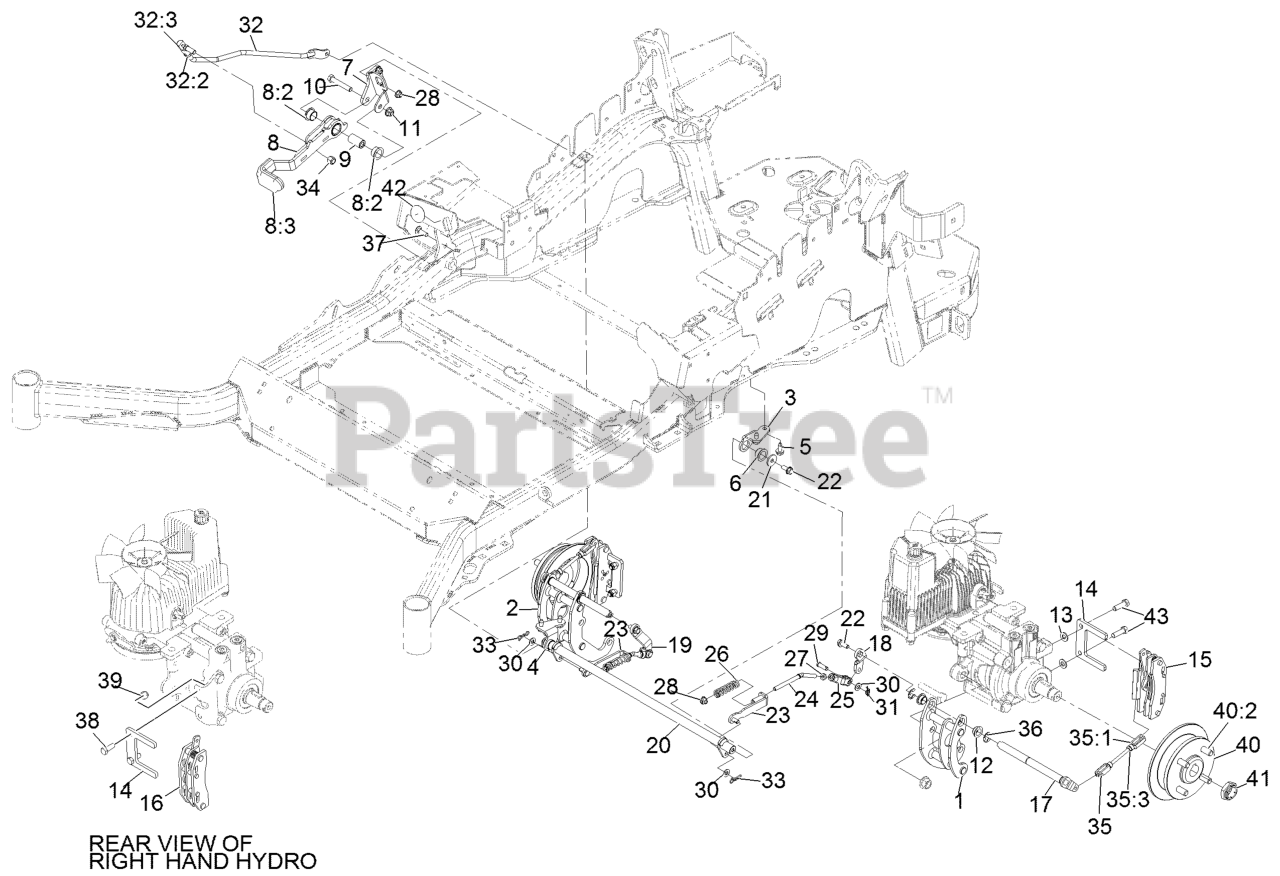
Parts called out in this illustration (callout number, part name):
1	WHEEL AND TIRE ASM
1:1	RIM ASM
1:2	TIRE
1:3	Stem-Valve
2	NUT-LUG
3	DECAL-TORQUE, WHEEL HUB LUG
